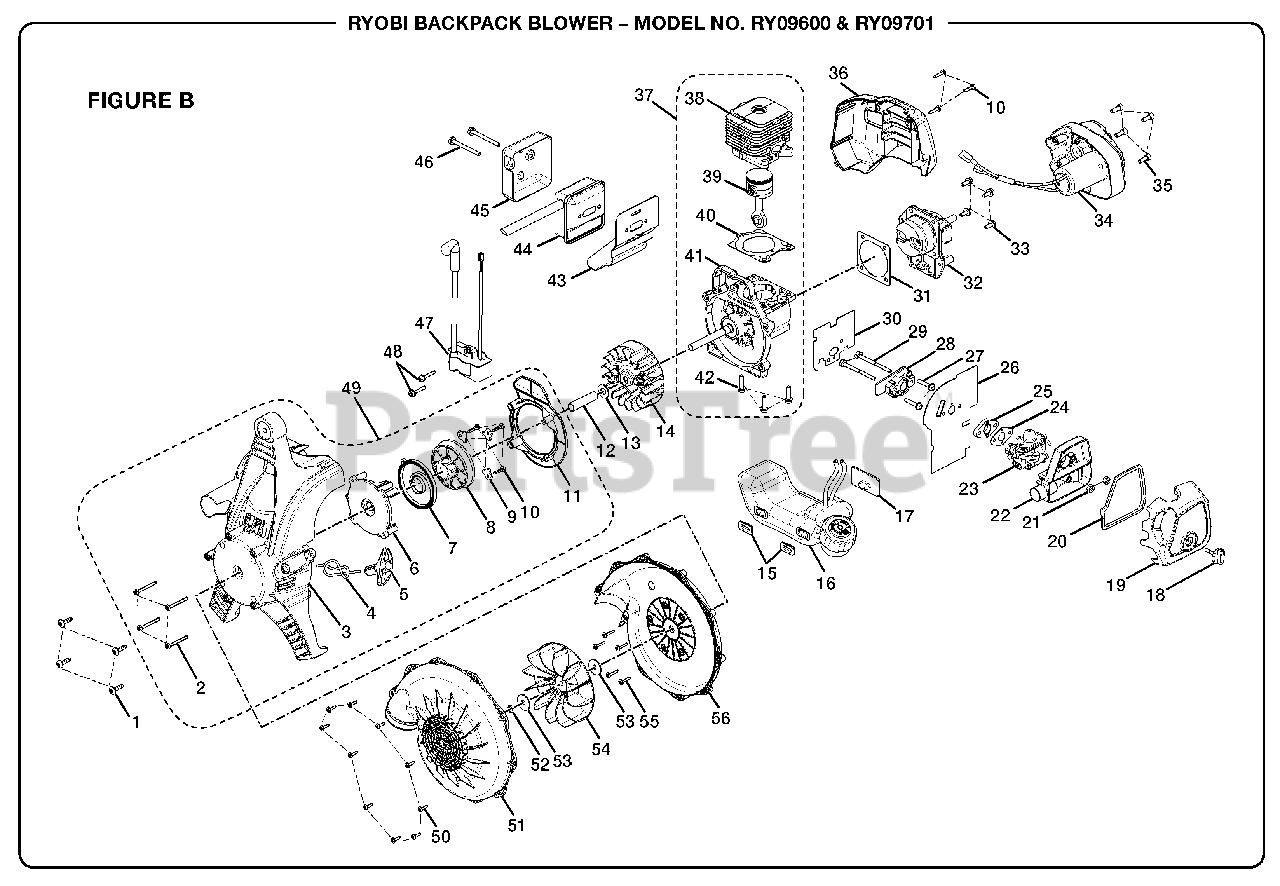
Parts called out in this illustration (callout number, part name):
1	Screw (10-24 x 3/4 in.)
2	Screw (M4 x 38 mm)
3	Low Housing Assembly
4	Starter Rope
5	Starter Grip
6	Starter Retaining
7	Spring and Container
9	Pulley Retainer
10	Screw (M4 x 18 mm)
11	Baffle Plate
13	Washer
14	Rotor Assembly
15	Bumper
16	Fuel Tank and Cap Assembly
18	Carburetor Knob
19	Air Box Cover
20	Air Box Gasket
21	Lock Nut (10-24)
22	Air Filter Base
23	Carburetor Assembly
24	Carburetor Gasket
25	Gasket
26	Carburetor Gasket
27	Screw (10-24 x 1 in. Pan Hd.)
29	Screw (10 x 2-1/2 in.)
30	Heat Dam Gasket
31	Crankcase Gasket
32	Crankcase Cover Assembly
33	Pan Head Screw (10-24 x 3/4 in.)
34	Electrical Start Assembly
35	Screw (M5 x 14 mm)
36	Rear Housing
37	Short Block Assembly
38	Cylinder
39	Piston w/ Rod Assembly
40	Cylinder Gasket
41	Crankcase Assembly
42	Screw (M5 x 0.8-20 mm)
43	Muffler Gasket
44	Muffler Assembly
45	Heat Shield
46	Screw (10-24 x 2-1/8 in.)
48	Screw (M4 x 25 mm)
49	Low Housing w/ Starter Assembly
50	Screw (10-14 x 3/4 in.)
51	Bottom Volute
53	Flat Washer
55	Screw (10-14 x 27 mm)
56	Top Volute
